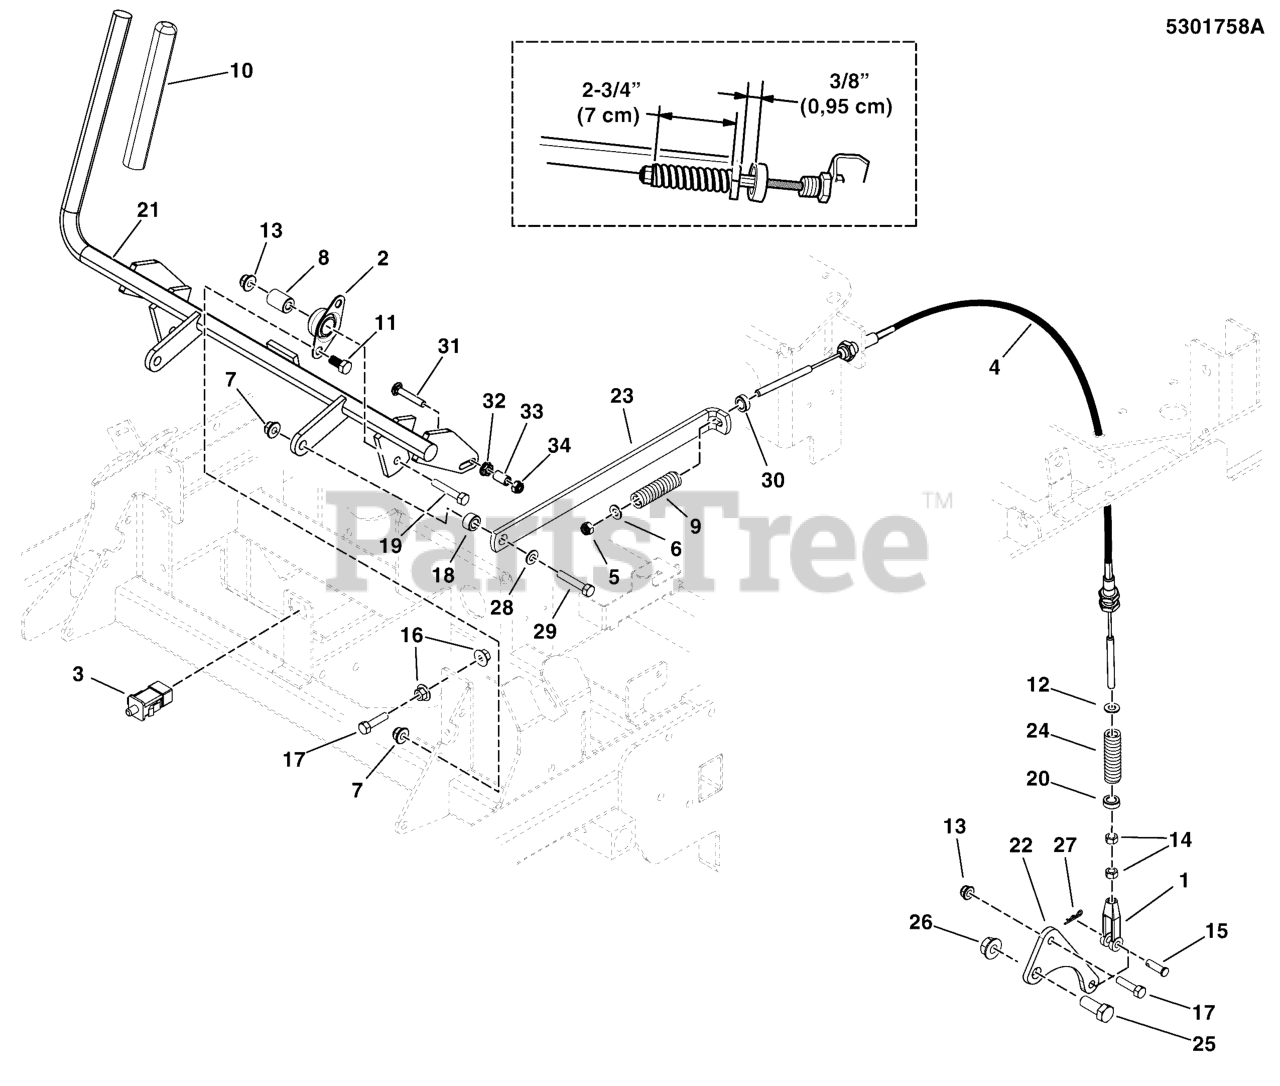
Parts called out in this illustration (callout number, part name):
1	CLEVIS, 5/16-24, STEEL, CLEAR ZINC
2	BEARING, 3/4" FLANGED, BRONZE
3	SWITCH, DP NO/NC SNAP-IN
4	CABLE, PARKING BRAKE, S200XT
5	NUT, 5/16-24 HEX NYLON LOCK
6	WASHER, 5/16" SAE
7	NUT, 3/8-16 HEX NYLOCK FLANGE
8	SPACER, .32 X .75 X 1.06, PM
9	SPRING, COMP. 1/2 ID X .140 WIRE X 3.25
10	GRIP, FOAM, 3/4 ID X 6 X .187
11	BOLT, 3/8-16 X 3/4" GD5 CZ
12	WASHER, 1/2 USS
13	NUT, 5/16-18 HEX NYLOCK FLANGE
14	NUT, 5/16-24 HEX
15	PIN, CLEVIS, 5/16 X 1, PLATED
16	NUT, 5/16-18 HEX SERRATED FLANGE (LARGE)
17	BOLT, 5/16-18 X 1-1/4 GD5 CZ
18	SPACER, .38 X .50 X .31, CZ
19	BOLT, 5/16-18 X 1-3/4 GD5 CZ
20	BUSHING, DECK PIVOT
21	WELD, BRAKE SHAFT, 210/320, NEUTRAL LOC
21	WELD, BRAKE SHAFT, 210/320 NEUTRAL LOC
22	PLATE, BRAKE ARM EXTENSION - BLK
23	LINK, BRAKE LOCK - BLK
24	SPRING-COMP, .930IDX5.00LGX.085WR - BLK
25	BOLT, 1/2-13 X 1-1/4 GD5 CZ
26	NUT, 1/2-13 HEX SIDE LOCK
27	PIN, COTTER, 1/8 X 3/4
28	WASHER, 3/8 SAE
29	BOLT, 3/8-16 X 1-1/4" GD5 CZ
30	COLLAR, 5/16 SET
31	BOLT, 1/4-20 X 1.500, GR5, SQ, ZINC/CLEA
32	NUT, 1/4-20 HEX SERR. FLANGE
33	SPACER, .25 X .38 X .63, CZ
34	NUT, 1/4-20 HEX NYLON LOCK
